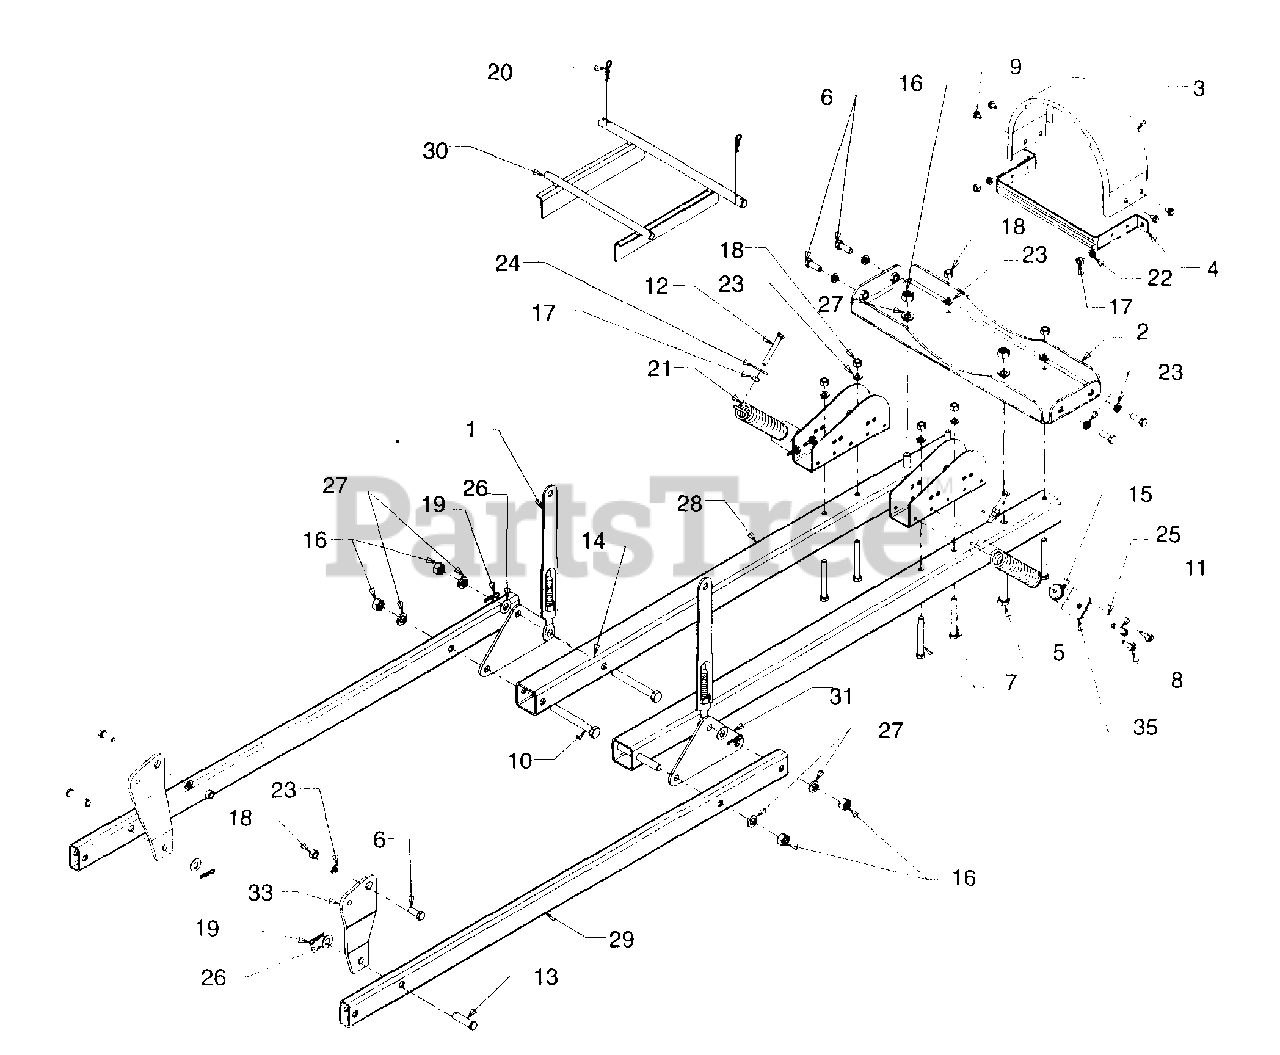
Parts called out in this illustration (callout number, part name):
1	LIFT ASM:DECK LINK:FRONT
6	HHCS:3/8-16:1.00:GR5:STD
7	HHCS:3/8-16:3.00:GR8:STD
8	HEX WASH SF TAPP SCR 5/16-18
9	SCR: TT:1/4-20:.375:HXINDWSH
10	HHCS:1/2-13:4.00:GR5:STD
11	HHCS:5/16-18:1.50:GR5:SPEC
12	HHCS:5/16-18:2.50:GR5:STD
13	PIN:CLV: .50 DIA X 1.59 LG
14	PIN:CLV: .50 DIA X .78 LG
16	NUT:1/2-13:GRA:HX
17	NUT:5/16-18:GRB:HX
18	NUT:3/8-16:GRB:HX
19	PIN:COT:INT .08 X 1.42
20	PIN:COT: .125 X 1.75 INTERNAL
21	SPR:EXTN:1.25 OD X 7.25
22	WASH:LOCK:5/16:REGULAR DUTY
23	WASH:LOCK:3/8:REGULAR DUTY
24	WASH:FL: .344 ID X 1.125 OD
25	WASH:BELVL:.340 ID X .872 OD
26	WASH:FL:.510 X 1.00 X .060
27	WASH:LOCK:1/2:REGULAR DUTY
28	TUBE:LIFT:2.0 X 2.0 X 42.0
31	BRKT:LIFT PLATE
35	BRKT:SPR:MT
